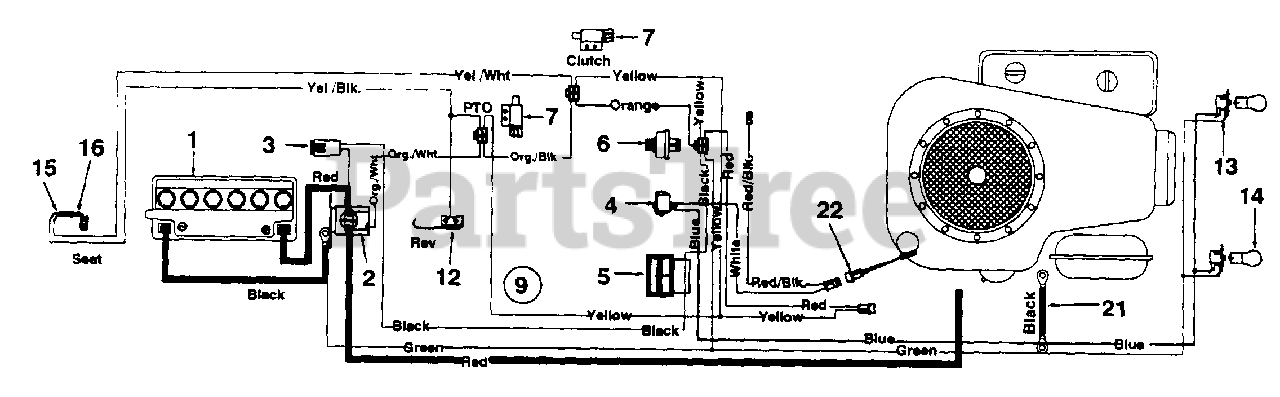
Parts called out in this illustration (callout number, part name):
1	Battery
2	Solenoid
3	Fuse 7.5 Amp
4	Light Switch
5	Ammeter
6	Ignition Switch
7	Safety Switch (Clutch)
9	Wire Harness
12	Safety Switch (Reverse)
13	Bulb Socket
14	Bulb
15	Safety Switch (Seat)
16	Safety Switch (Seat)
21	Ground Wire 7.5" Lg.
22	Harness Adapter
